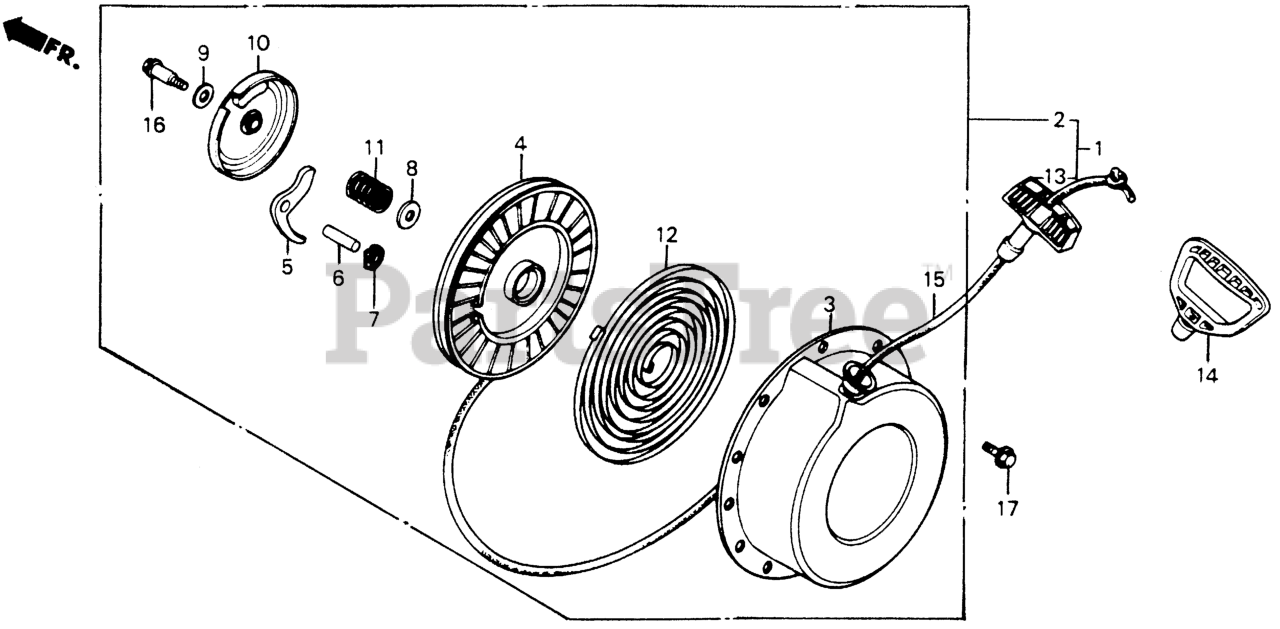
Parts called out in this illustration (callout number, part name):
1	STARTER ASSY., RECOIL *R8* (BRIGHT RED)
2	STARTER ASSY., RECOIL *R8* (BRIGHT RED)
3	CASE, RECOIL STARTER *R8* (BRIGHT RED)
3	CASE, STARTER *R8* (BRIGHT RED)
4	REEL, STARTER (NOT AVAILABLE)
5	RATCHET, STARTER
6	SHAFT, RATCHET
7	PLATE, GUIDE
8	PLATE A, FRICTION
9	PLATE B, FRICTION
10	COVER, REEL STARTER
11	SPRING, FRICTION
12	SPRING, RETURN
13	GRIP, STARTER
14	GRIP, STARTER
15	ROPE, STARTER (#5X55") (N/A: USE P/N 08550-ZG921-11)
16	BOLT, REEL COVER
17	BOLT, FLANGE (6X8)
